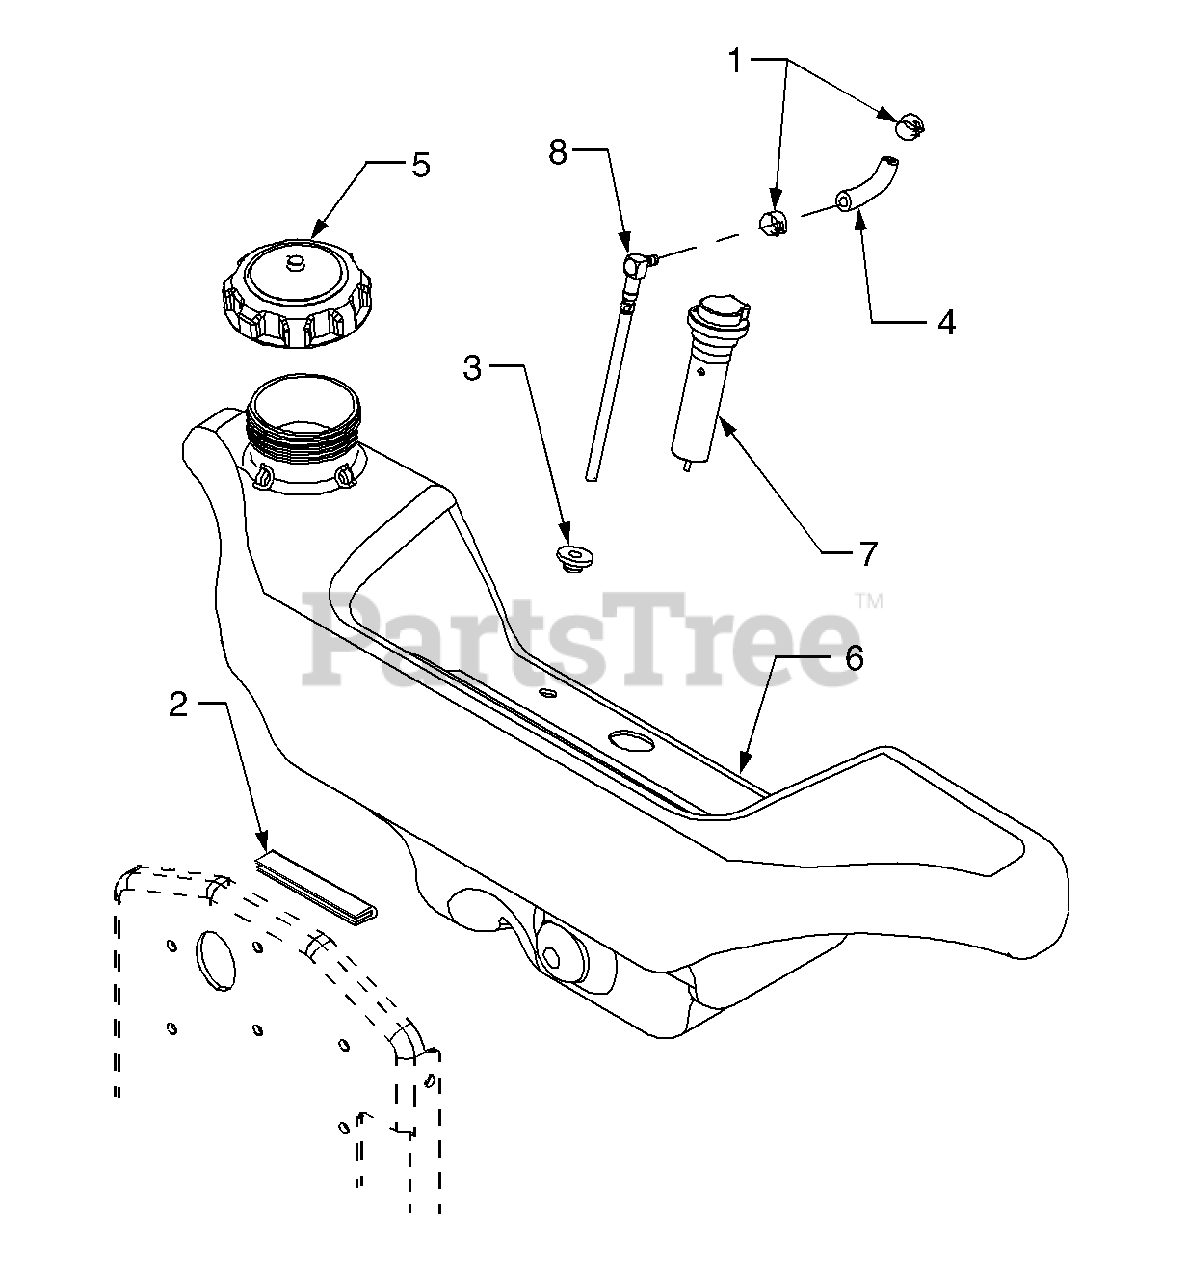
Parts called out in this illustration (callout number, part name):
1	Clamp, Hose
2	Trim, Tank Protector
3	Bushing, Rubber
4	Fuel Line (68in. Lg)
5	Cap, Fuel
6	Tank, Fuel, 4.5 Gallon
7	Sensor, Low Fuel
8	Fitting, Fuel Pickup
